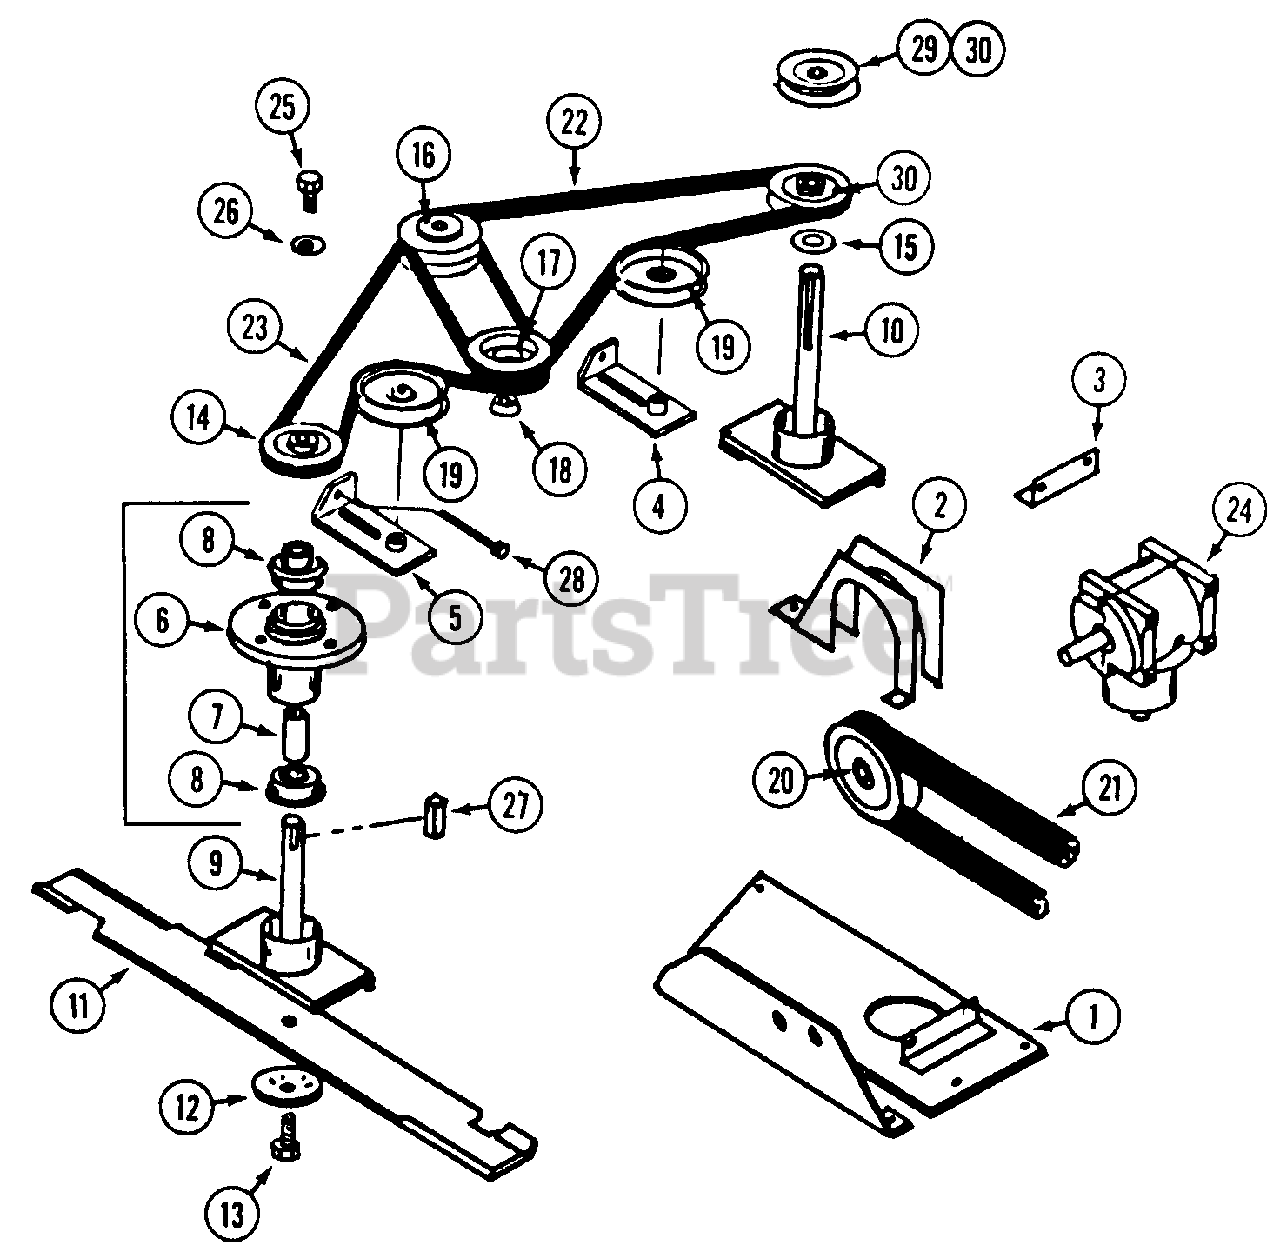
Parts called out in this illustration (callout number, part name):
1	MOUNT - gear box
2	GUARD - belt
3	ANGLE - gear box mount
4	TIGHTENER - belt
5	TIGHTENER - belt
6	HOUSING - spindle
7	SPACER - spindle
8	BEARING - spindle
9	SHAFT - spindle
10	SHAFT - spindle
11	BLADE
12	WASHER - blade
13	BOLT - 3/8"-24 x 1-1/4"
14	PULLEY - spindle
15	WASHER - spacer
16	PULLEY - spindle, double
17	PULLEY - gear box output
18	HUB - pulley
19	PULLEY - idler
20	PULLEY - gear box input
20	PULLEY - gearbox input
21	BELT - drive
22	BELT - deck
25	BOLT - 5/16"-24 x 3/4"
26	WASHER - 5/16", 10 ga.
27	KEY - 3/16" x 3/16" x 1"
28	BOLT - 1/4"-20 x 4"
29	PULLEY - spindle
30	PULLEY - spindle
